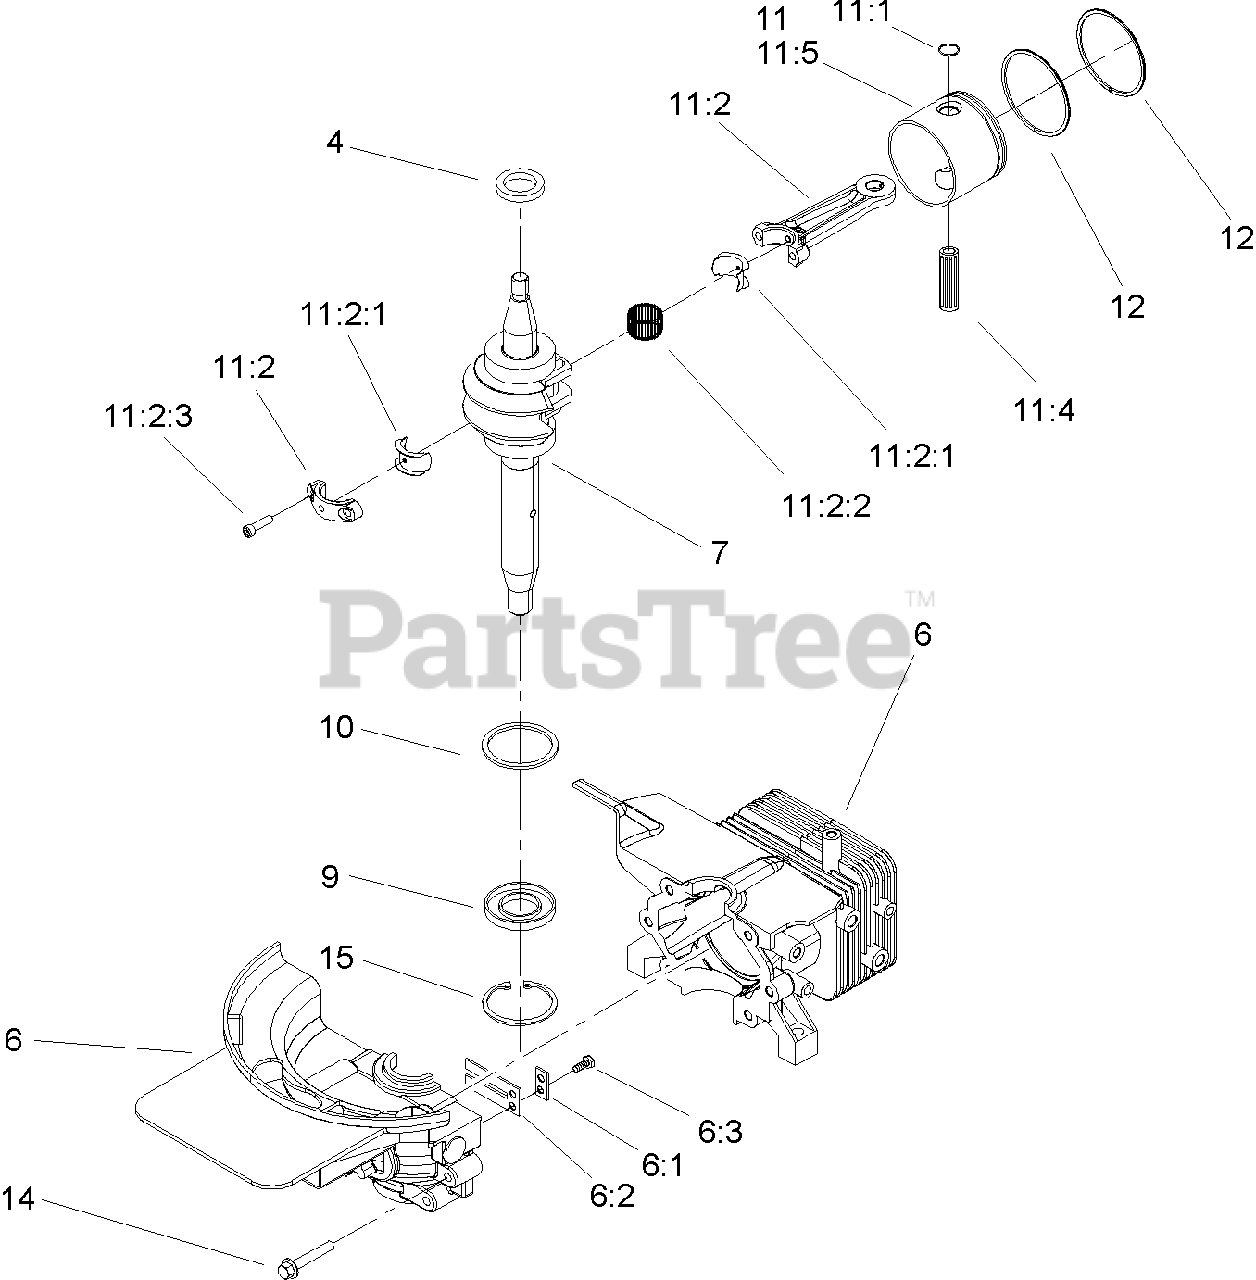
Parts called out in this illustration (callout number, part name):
4	SEAL-OIL
6	CYLINDER AND CRANKCASE ASM
6:1	PLATE-BACKUP, REED
6:2	REED-CARBURETOR
6:3	SCREW-HH
7	CRANKSHAFT AND BEARING ASM
9	SEAL-OIL
10	RING-RETAINING, EXT.
11	Piston And Connecting Rod ASM
11:1	RING-RETAINING
11:2	CONNECTING ROD ASM
11:2:1	LINER ASM
11:2:2	BEARING-NEEDLE
11:2:3	SCREW-HSH
11:4	PIN-WRIST
11:5	PISTON AND RINGS ASM
14	SCREW-HHF
15	RING-RETAINING
